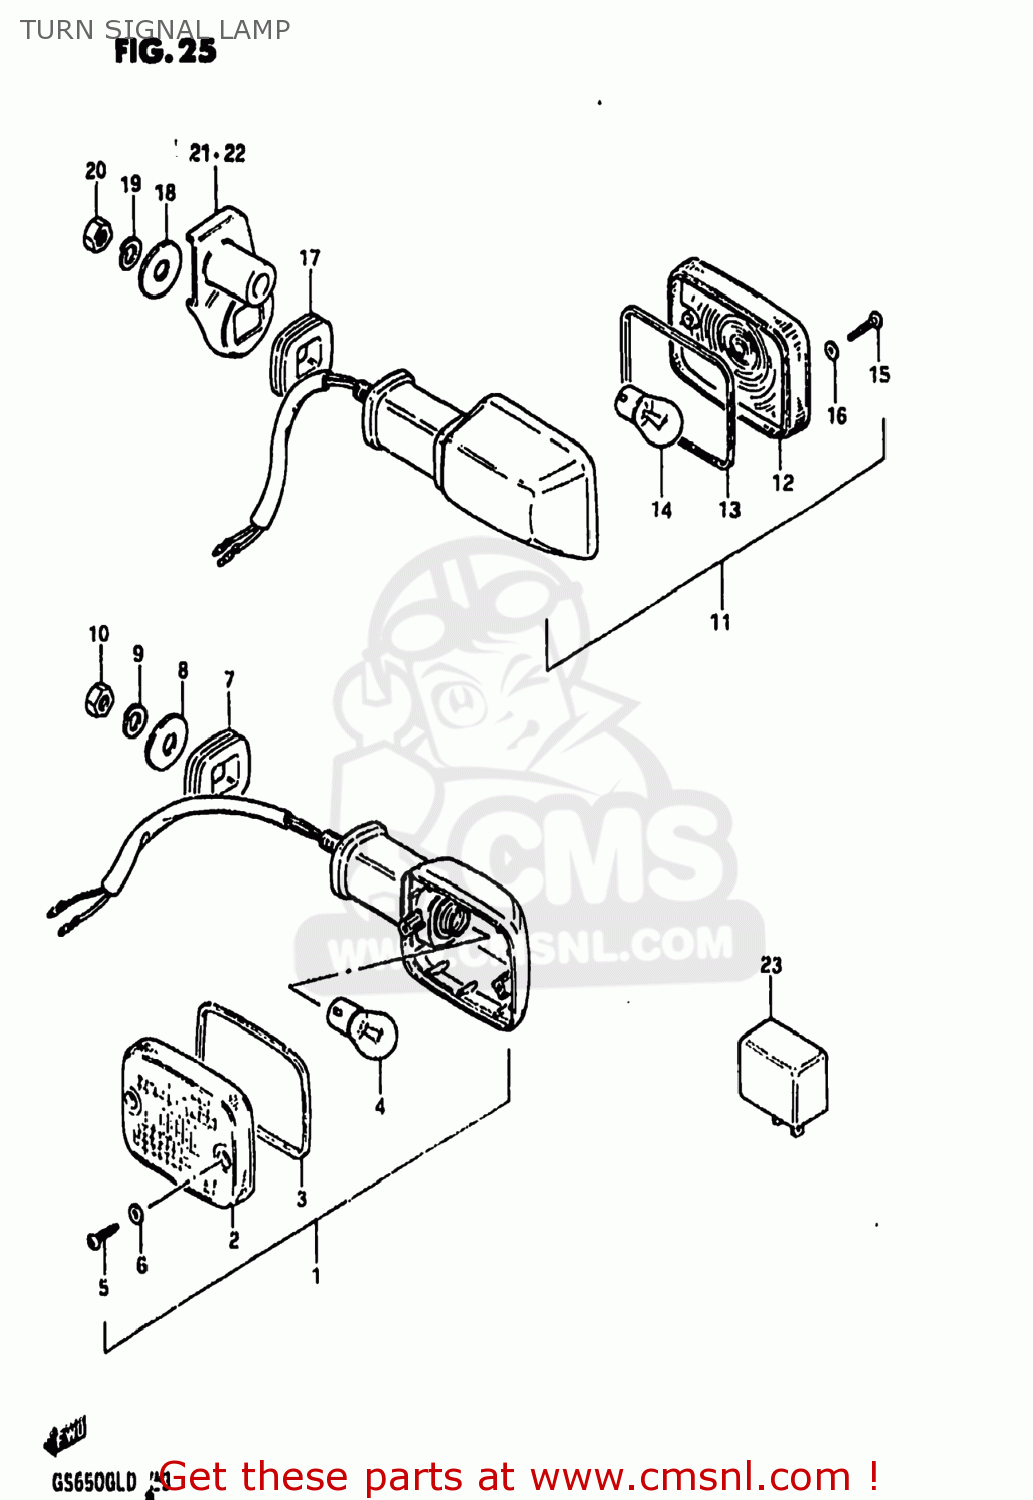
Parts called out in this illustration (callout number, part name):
1	LAMP ASSEMBLY,FRONT TURN SIGNAL
2	LENS
3	GASKET (NAS)
4	BULB(12V23W,STANLEY,A4577A)
5	SCREW
6	GASKET (NAS)
7	CUSHION
8	WASHER (10.5X30X2.3)
9	LOCK WASHER
10	NUT
11	LAMP ASSEMBLY,REAR TURN SIGNAL
12	LENS
13	GASKET (NAS)
14	BULB(12V23W,STANLEY,A4577A)
15	SCREW
16	GASKET (NAS)
17	CUSHION
18	WASHER (10.5X30X2.3)
19	LOCK WASHER
20	NUT
21	BRACKET,REAR TURN SIGNAL
22	BRACKET,REAR TURN SIGNAL
23	RELAY,TURN SIGNAL
